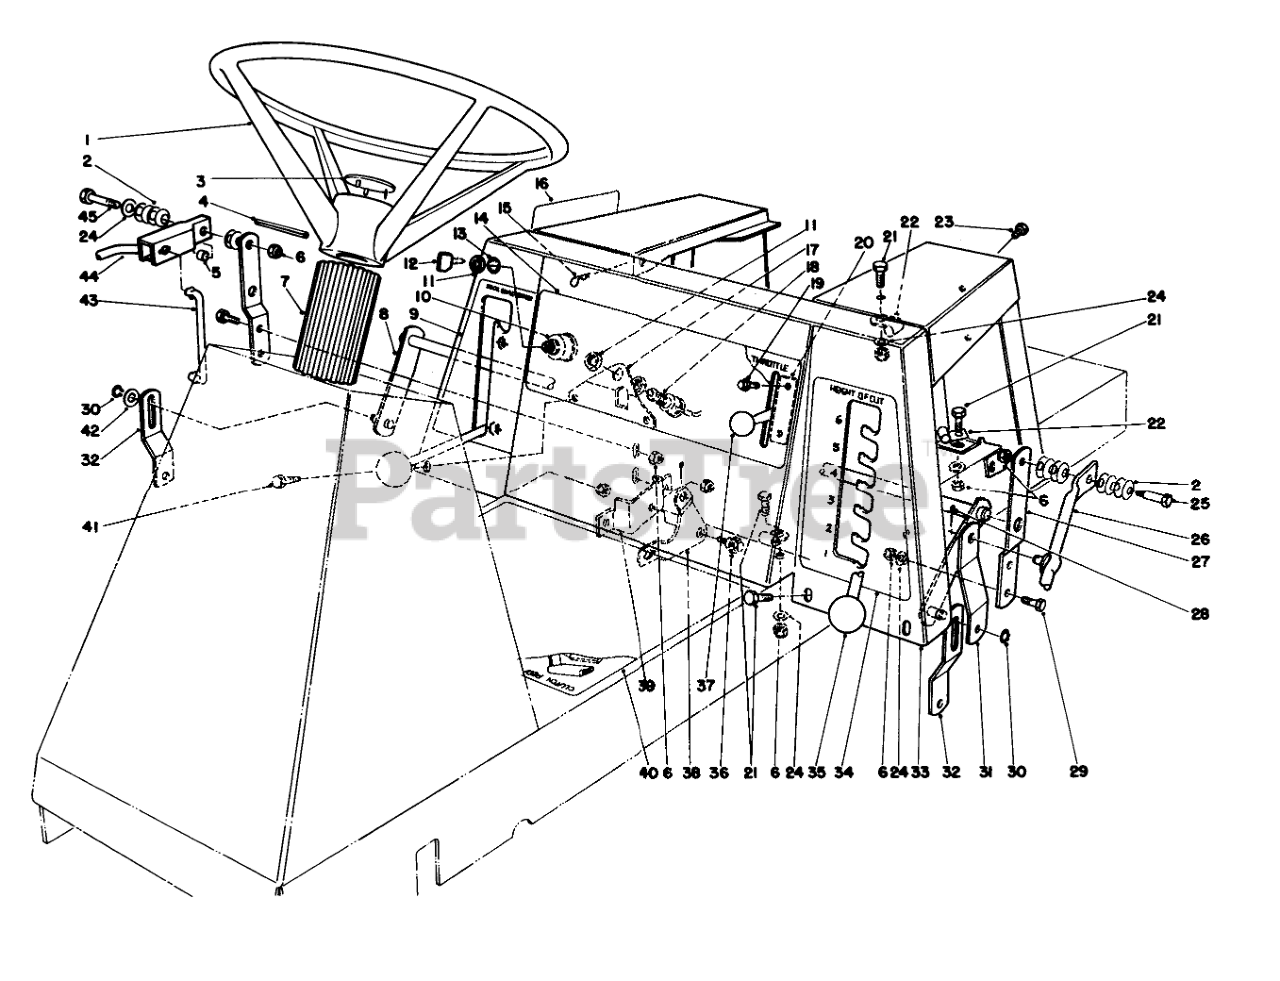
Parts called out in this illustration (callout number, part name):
1	Steering Wheel Assembly (Incl. Ref. #3)
2	Belleville Washer
3	STEERING WHEEL INSERT
4	PIN-ROLL
5	Spacer-Pivot
6	NUT-LOCK, NI
7	COVER-STEERING SHAFT
8	Arm
9	DECK ENGAGE DECAL
10	Switch-Ignition (Incl. Ref. #11-13)
11	NUT-HH
12	KEY-IGNITION
13	WASHER-TOOTH, INTERNAL
14	IGN & THROTTLE DECAL
15	PIN-COTTER
16	DECAL - SHIFT PATTERN
17	SWITCH MT BRKT
18	Switch-Deck (Incl. Ref. #11)
19	SCREW-HWHTF
20	Control-Throttle (Incl. Ref. #37)
21	SCREW-HH
22	CLAMP
23	SCREW-HH
24	WASHER-PLAIN
25	BOLT-SHOULDER
26	HOC LEVER WA B
27	Bracket
28	PIN-COTTER
29	SCREW-HH
30	RING-RETAINING
31	HOC ENGAGE BRKT R
32	Link-Deck Suspension
33	Body-Seat
34	HOC DECAL
36	SCREW-SHOULDER
37	Knob
38	DECK ENGAGE BELLCRANK
39	BELLCRANK MTG BRKT
40	INSTRUCTION DECAL
41	SCREW-HH
42	WASHER-FLAT
43	BELLCRANK LINK(PLTD)
44	SHIFT LEVER WA B
45	SCREW-HH
